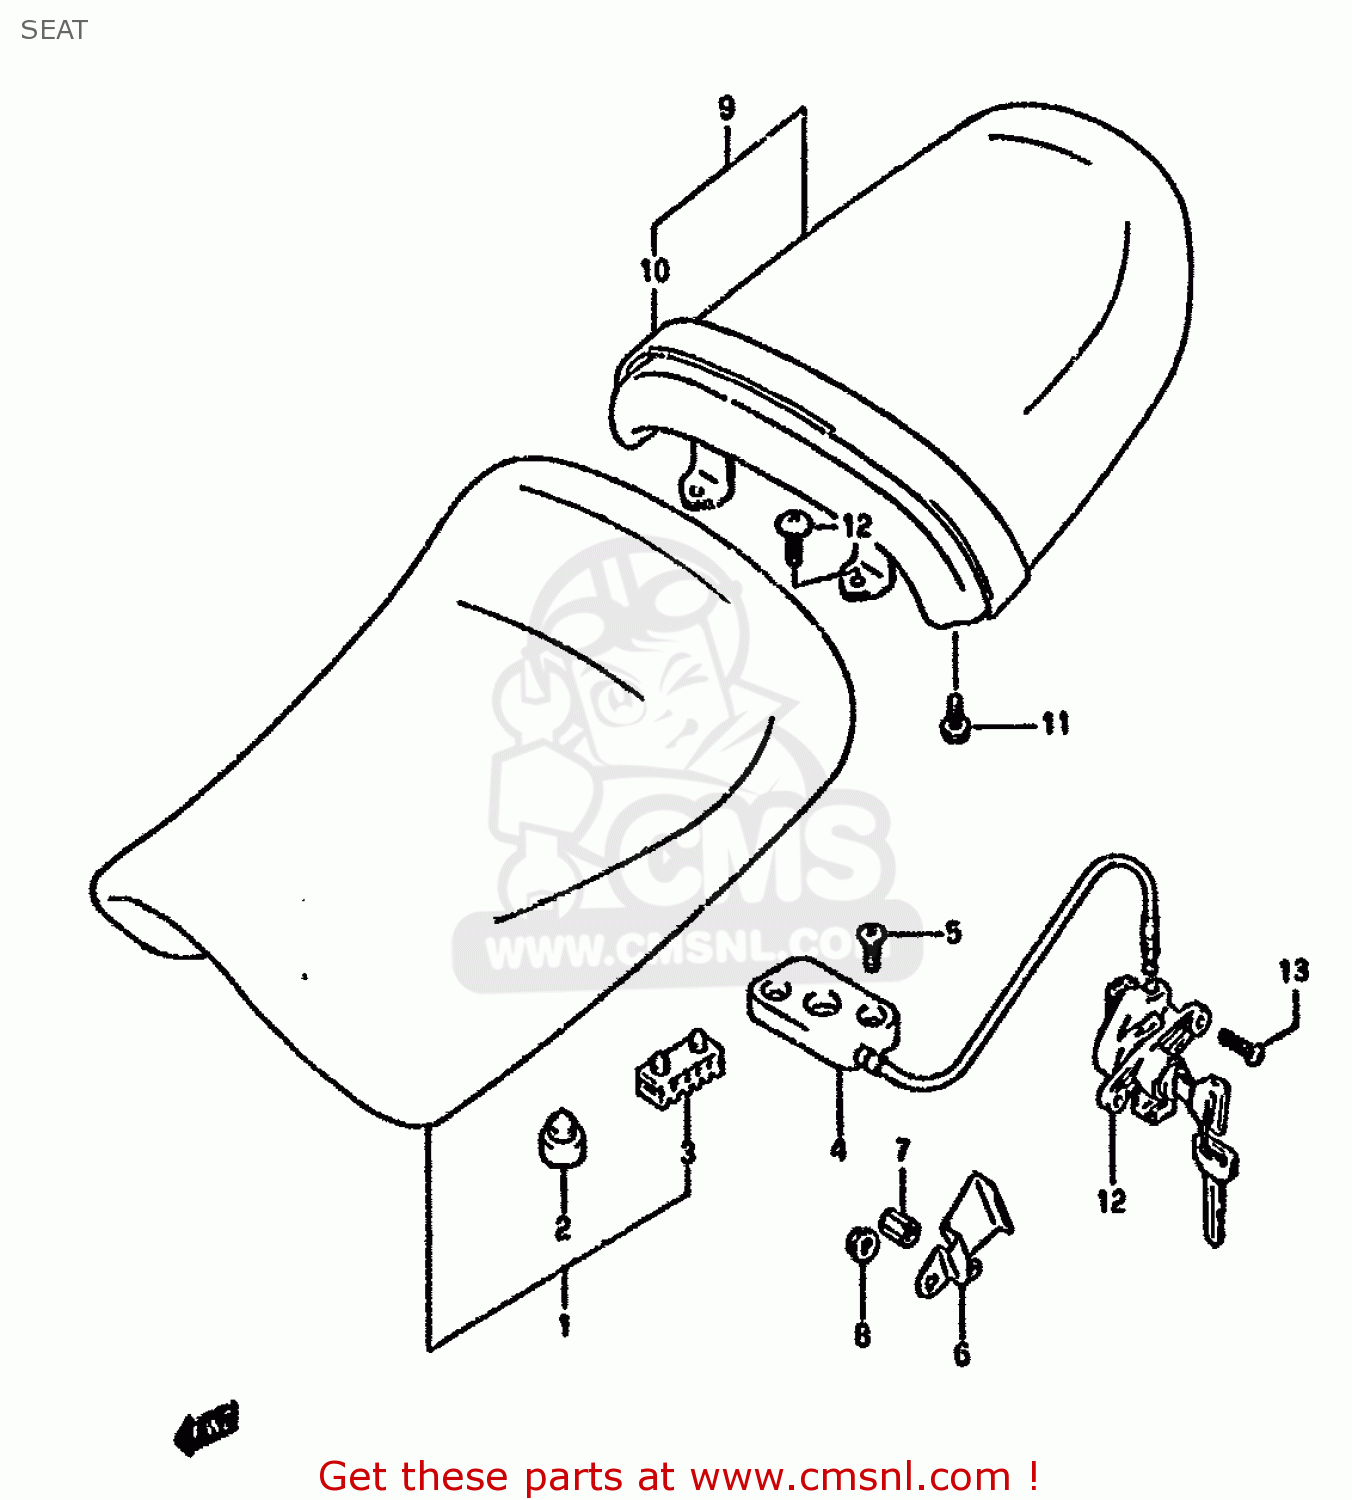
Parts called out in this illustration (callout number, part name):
1	SEAT ASSEMBLY
2	CUSHION
3	CUSHION,SEAT(40X20X15)
4	BRACKET,SEAT SUPPORT
5	SCREW
6	PLATE,SEAT LOCK CABLE
7	NUT
8	NUT
9	SEAT ASSY,PILLION
10	BAND,SEAT
11	SCREW(6X12)
12	LOCK SET,SEAT & HELMET
13	SCREW(6X20)
